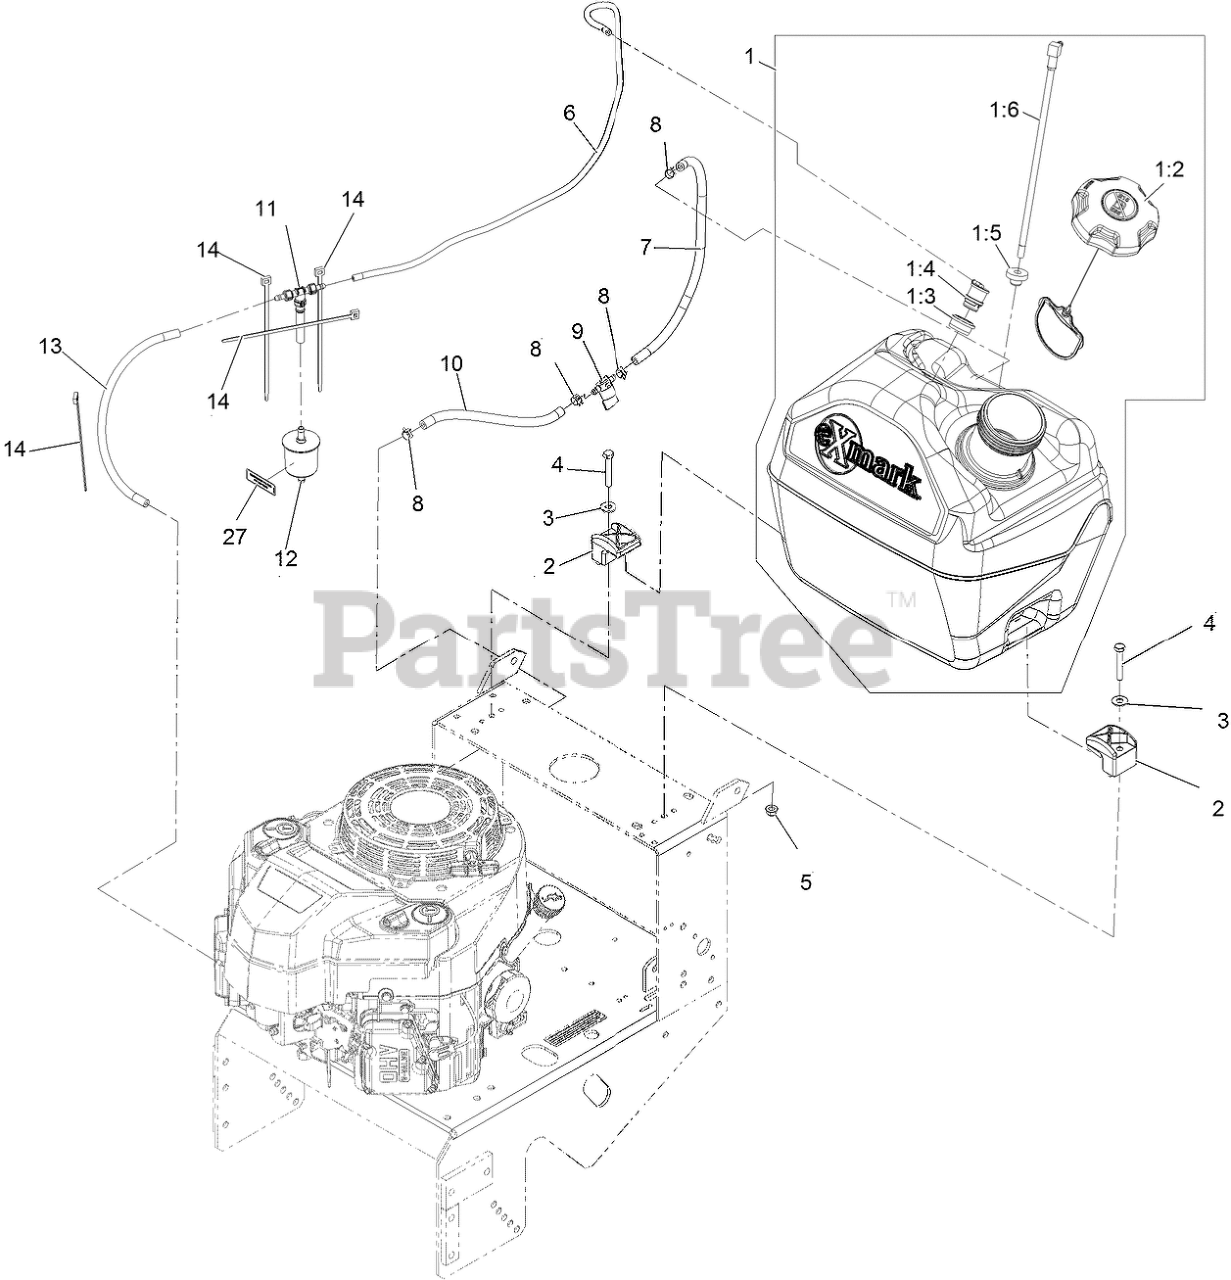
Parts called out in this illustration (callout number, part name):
1	ASM, FUEL TANK 5 GAL
1:2	CAP-FUEL, RATCHETING
1:3	GROMMET
1:4	VALVE-VENT, FUEL
1:5	BUSHING
3	WASHER-FLAT
4	SCREW-HH
5	NUT-HF, NI
6	HOSE-EMISSIONS
7	HOSE-FUEL
8	CLAMP-HOSE
9	VALVE-FUEL
10	HOSE-FUEL
11	TEE AND CHECK
12	FILTER-FUEL
13	HOSE-FUEL
14	TIE-PLASTIC
27	DECAL-FILTER, EMISSIONS
